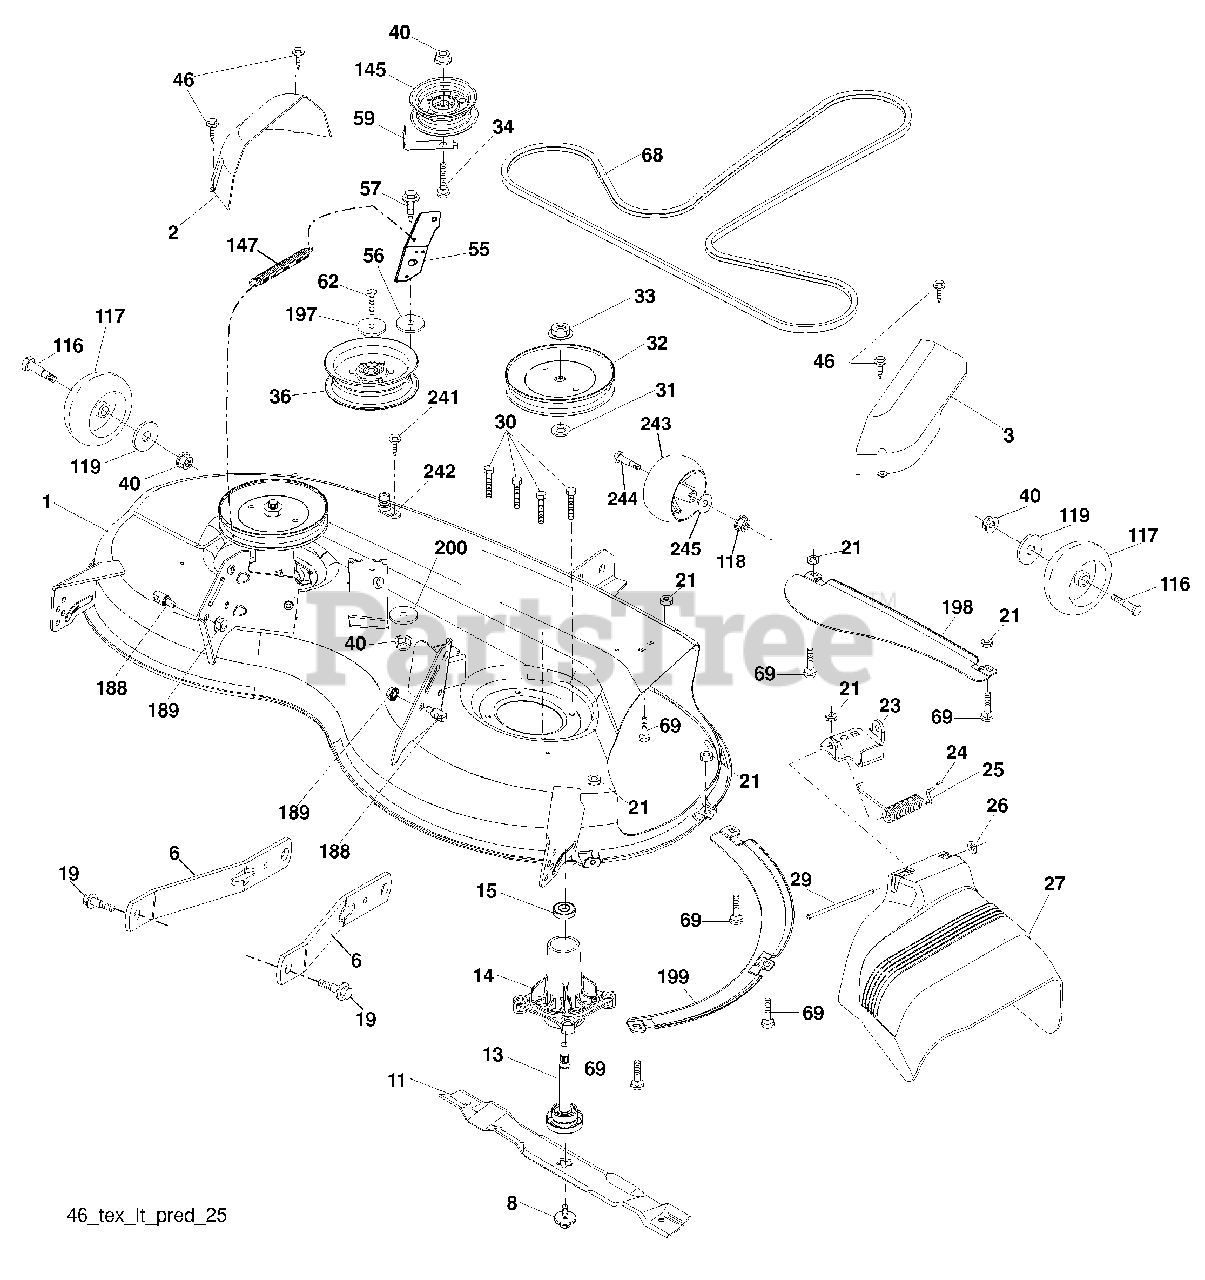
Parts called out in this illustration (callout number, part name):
1	Mower Housing
2	Cover Mandrel RH
3	Cover Mandrel LH
6	Arm Suspension
8	Bolt/Washer asm 7/16-20 unf
11	Blade Mower Hi Lift
13	Shaft Assembly, Mandrel
14	Housing, Mandrel
15	Bearing, Ball, Mandrel
19	Bolt, Shoulder
21	Nut
23	Bracket, Deflector
24	Cap, Sleeve
25	Spring, Torsion, Deflector
27	Shield, Deflector
29	Rod, Hinge
30	Screw Thdrol Rolling Wsh Hd
31	Washer, Spacer
32	Pulley, Mandrel
33	Nut, Toplock, Flanged
34	Bolt Carr Sh. 3/8-16 x 1-1/2 Gr. 5
36	Pulley, Idler, Flat
40	Nut, Lock Flg. 3/8-16 unc
55	Arm, Idler
56	Spacer, Retainer
57	Screw Hexwsh Thd 3/8-16 x 1
59	Guard, Tuv Idler (94)
62	Bolt 3/8-16 unc x 2-1/4 Gr. 5
68	V-Belt
69	Bolt
116	Bolt, Shoulder
117	Wheel, Gauge
118	Nut Centerlock 3/8-16 unc
119	Washer 13/32 x 1-1/2 x 11 Ga.
145	Pulley Idler
147	Spring Return
188	Stud Fastener
189	Nut Lock Hex Flange
197	Washer 13/32 x 13/16 x 12 Ga.
198	Baffle Center Front
199	Baffle Front RH
200	Washer 13/32 x 1 x 1/2 11 GAHRD
242	Washout Port
243	Wheel Gauge Half Spoked
244	Bolt Shoulder "A" 2.41. "B" 1.66
245	Washer 3/8 x 7/8 x 14 Ga.
